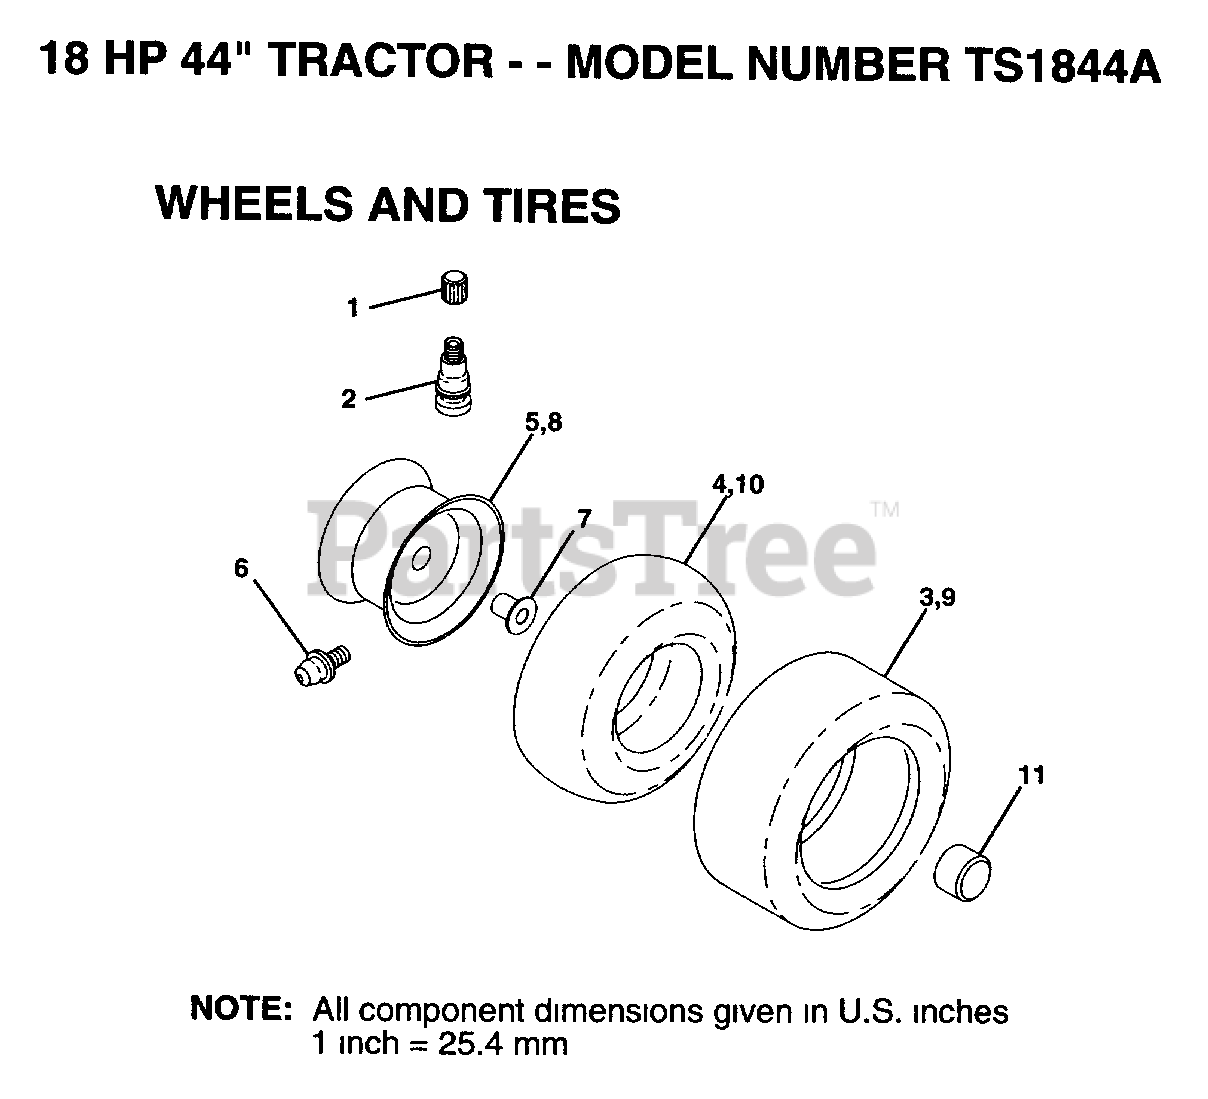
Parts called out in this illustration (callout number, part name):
1	VALVE CAP
2	VALVE STEM LT
4	TUBE.5.3/4.5/6
6	FITTING LT
7	"FLANGE, BEARING"
10	TUBE.23X8/10-12
11	HUB CAP
